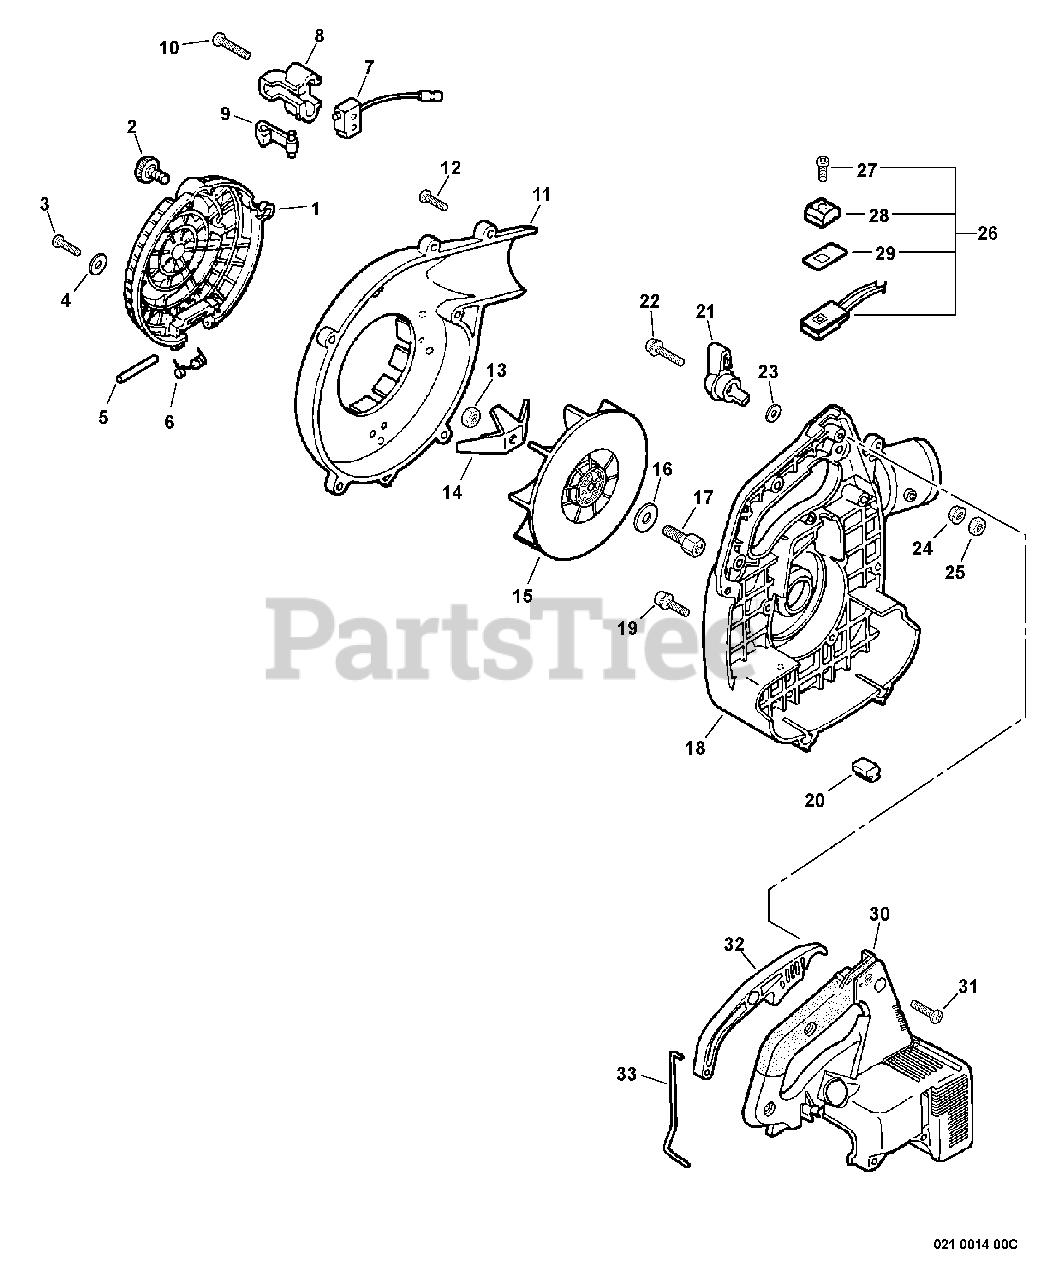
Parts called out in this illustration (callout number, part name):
1	GUARD, DEBRIS
2	THUMBSCREW
3	SCREW - 5X14
4	WASHER - 5
7	IGNITION SWITCH ASSY
8	BRACKET, SWITCH - BLACK
9	LEVER, SHUT OFF ACTUATOR
10	SCREW - 4X22
11	COVER, FAN - LEFT -- ORANGE
12	SCREW - 5X20 -- TAPPING
14	BLADE, SHREDDER
16	WASHER - 8
17	HUB, FAN
18	COVER, FAN - RIGHT -- ORANGE
19	SCREW - 4X22
21	LEVER, THROTTLE - ORANGE
22	SCREW - 5X25
23	WASHER - 5
24	NUT - 5 -- FLANGE
26	IGNITION SWITCH ASSY
27	SCREW - 3X10
28	KNOB, SWITCH - ORANGE
29	COVER, SWITCH - STOP
30	COVER, ENGINE - ORANGE
31	SCREW - 5X20 -- TAPPING
32	TRIGGER, THROTTLE - ORANGE
33	ROD, THROTTLE
